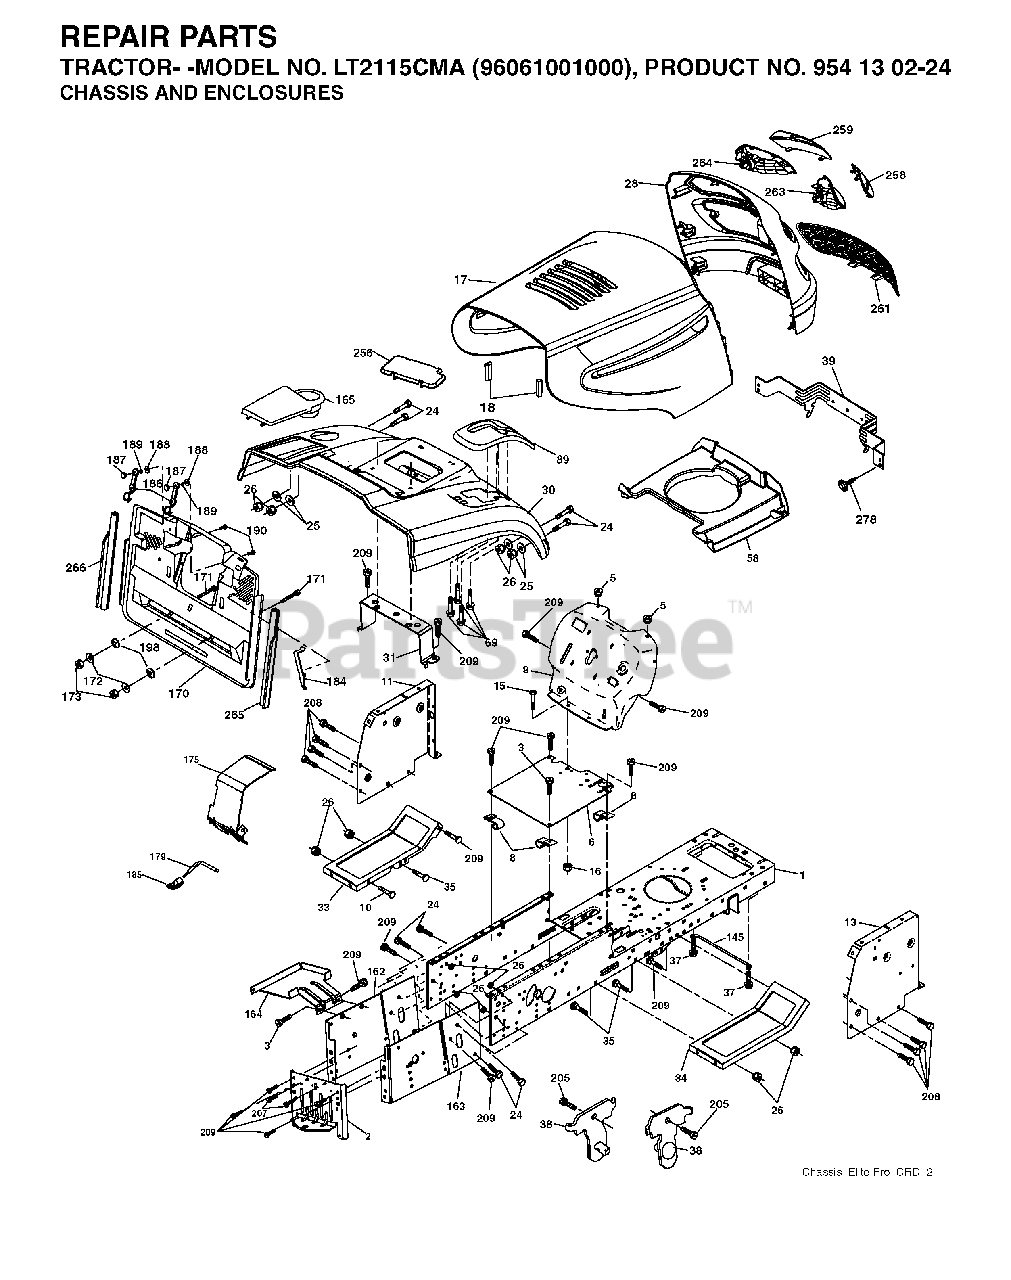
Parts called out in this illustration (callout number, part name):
1	CHASSIS
3	SCREW 3/8-16X3/4
5	BUMPER.RUBBER.HOOD
8	CLIP,INSULATOR
10	BOLT D
11	PANEL.DASH.LH.LTX
13	PANEL DASH RH
16	NUT
18	BUMPER.HOOD.LARGE.1.75"
25	WASHER
26	NUT
31	BRACKET SUPPORT FENDER
39	BRACKET PIVOT LASER
69	SCREW.HI-LO.CONSOLE
145	ROD PIVOT CHASSIS/HOOD
164	SUPPORT
171	BOLT
172	WASHER
186	LATCH ASSY
187	WELDNUT
189	LOCKWASHER
207	SCREW, 5/16-18 X 1/2
208	SCREW 3/8-16X1/2
209	SCREW, 3/8-16X3/4
263	BEZEL GRILL RH
264	BEZEL GRILL LH
278	SCREW
